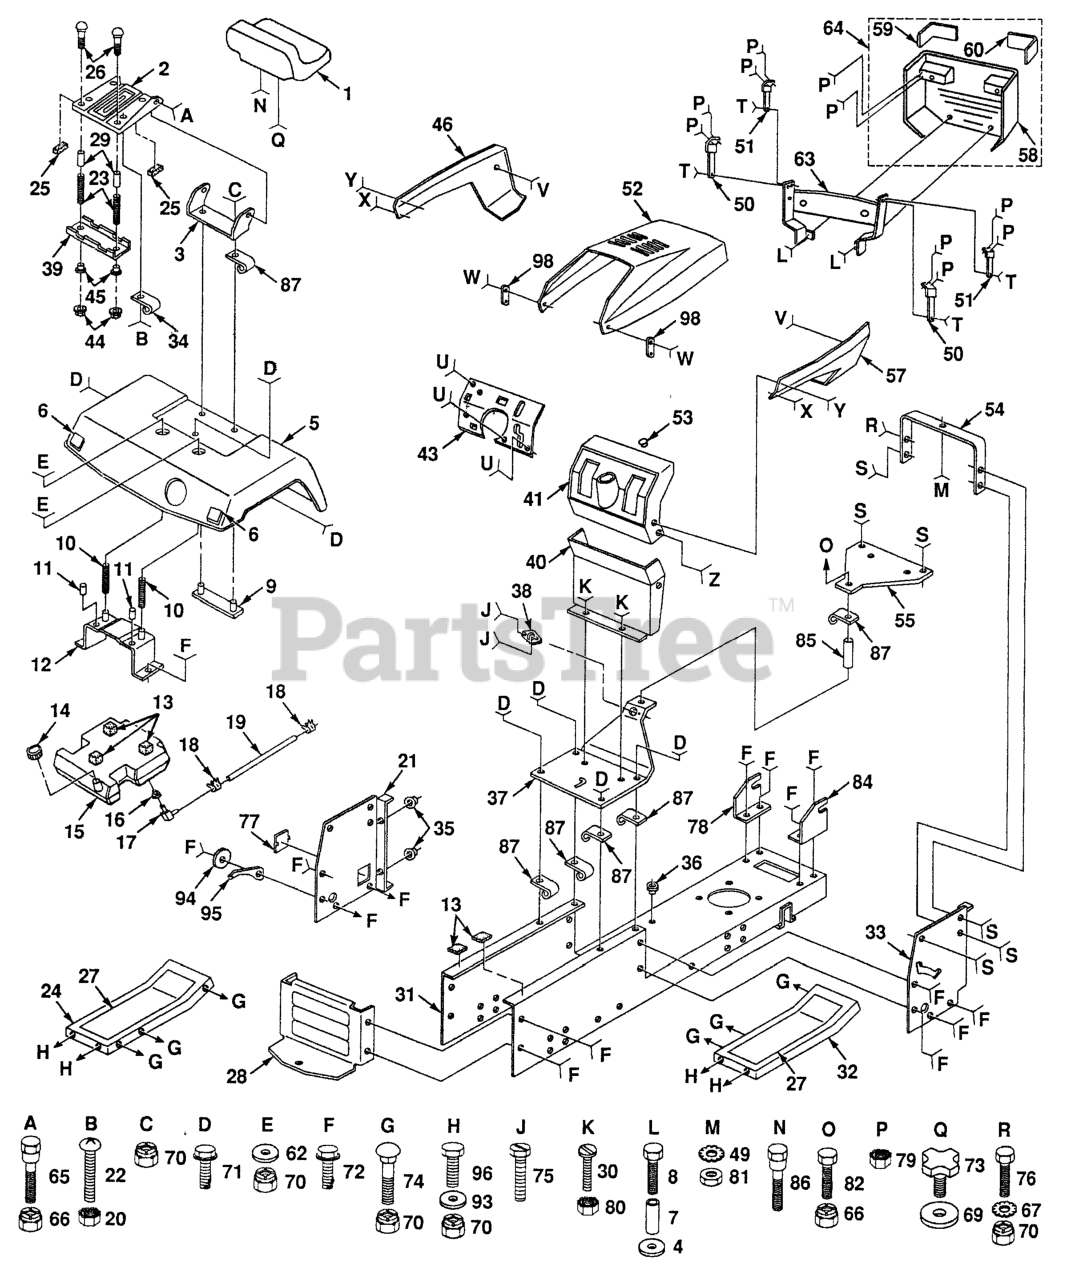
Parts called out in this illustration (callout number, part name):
1	SEAT
3	BRKT,SEAT PIVOT
4	WASHER PM
5	FENDER
6	REFLECTOR-TAIL YT
9	STRAP-FENDER YT
10	SPRING COMPRESSION
11	NUT-PUSH YT
12	BRACKET-FENDER YT
13	PAD-SPACER T
14	FUEL CAP ASS'Y
15	FUEL TANK LT
16	BUSHING OUTLET T
17	FUEL TANK STEM GT
18	HOSE CLAMP
19	FUEL LINE T
20	Nut, Keps #10
21	PANEL DASH LH NLA
23	SPRING COMPRESSED
24	ROLL PIN NLA
25	STRIP FORM
26	Bolt, Carriage 1/4 - 20 x 1-1/4
27	PAD FOOTREST T
28	DRAWBAR
29	SPACER SPLIT
30	Screw, Mach. Cr. Threaded 5/16-18x3/4
32	PAD,SPACER
33	PANEL LT NLA
34	CLIP T
35	SNAP BUSHING T
36	SNAP BUSHING T
37	SADDLE
38	BUSHING LT
39	BRKT SWITCH
40	DASH LOWER YT NLA
41	DASHBOARD
43	STRAP ASSY T
44	NUT T
46	PANEL,SIDE LH
49	Washer, Lock, External Tooth 1/4
50	STRAP ASSY LT
51	STRAP ASSY LT
52	HOOD
53	PLUG BUTTON T
54	SUPPORT ASS'Y
55	PLATE SUPPORT T NLA
57	PANEL,SIDE RH
58	GRILL
59	LENS LH
60	LENS RH
62	WASHER
63	SUPPORT ASS'Y
64	GRILL COMPLETE
65	BOLT, SHOULDER LT
66	LOCKNUT
67	LOCKWASHER
71	SCREW LT
72	SCREW
73	KNOB 1/2" YT
74	Bolt, Carriage 3/8 - 16 x 3/4
75	SCREW LT
76	BOLT
77	COVER ACCESS
78	SUPPORT LH YTH
79	NUT
80	NUT
81	NUT
82	Bolt, Hex 5/16 - 18 x 2
84	SUPPORT RH YTH
86	BOLT,SHOULD
87	CLIP T
93	WASHER
95	POINTER HGT INDAT
98	LATCH.HOOD.
